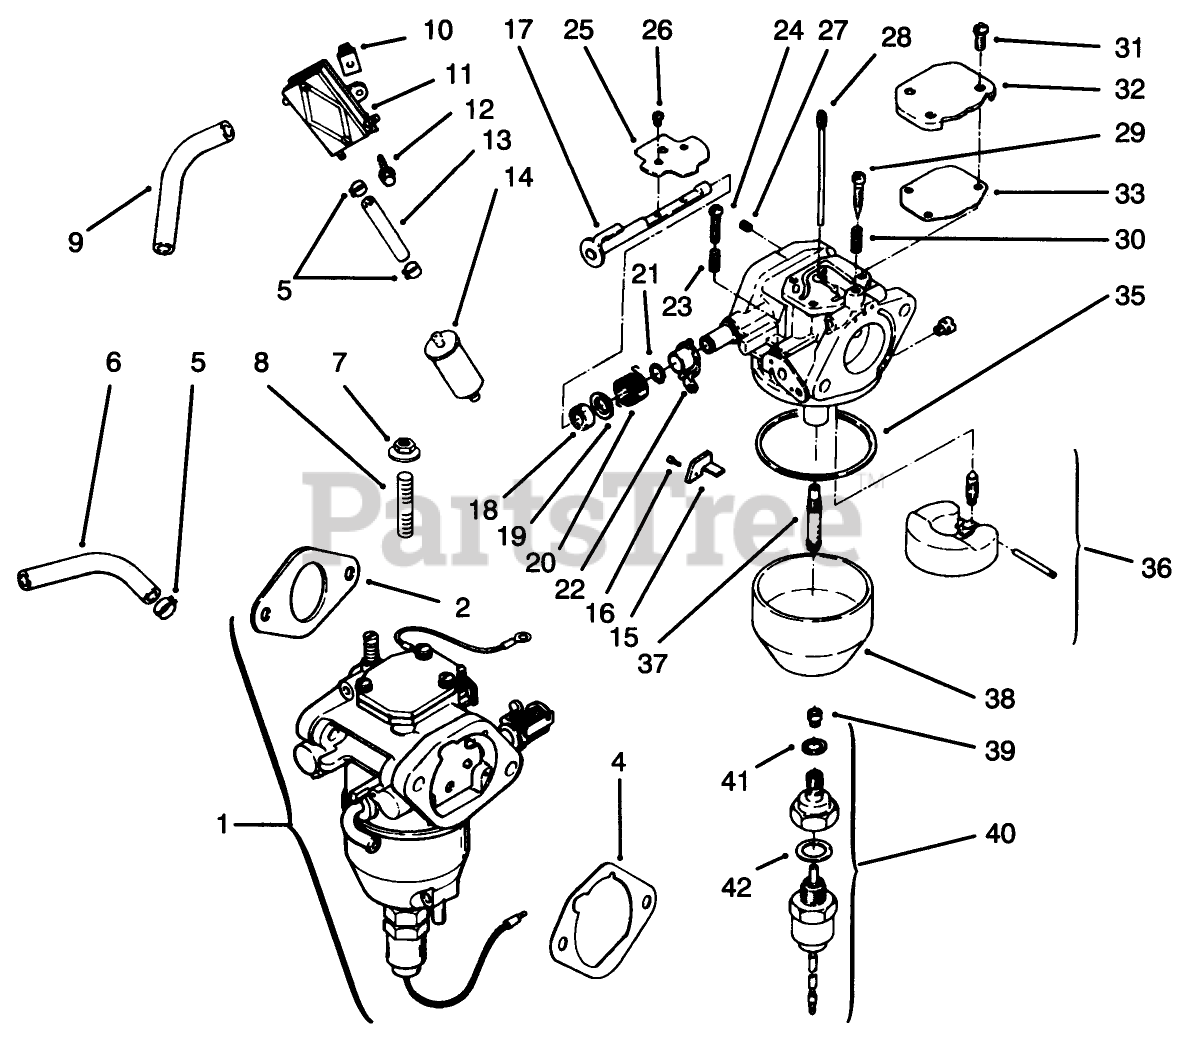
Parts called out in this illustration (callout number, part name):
1	Kit-Carb INCL 2/4/15-42 (Only On: 72103)
2	Gasket-Carburetor (Only On: 72103)
4	Gasket-A/C Base (Only On: 72103, 72083)
5	Clamp
6	Line-Fuel 10 1/2" (Only On: 72103, 72083)
8	Stud M6x1.0x95 (Only On: 72103, 72083)
9	Line-Fuel 12" (Only On: 72103)
11	Pump-Fuel
13	Line-Fuel 3 1/2" (Only On: 72103)
14	Filter-Fuel (Only On: 72042,72043,72062,72063)
15	Bracket-Throttle Stop (Only On: 72103, 72083)
16	Screw M2.5X45X5.5 (Only On: 72103)
17	Shaft-Choke (Only On: 72103, 72083)
18	Washer (Only On: 72103, 72083)
19	Collar-Choke (Only On: 72103, 72083)
20	Spring-Choke Return (Only On: 72103, 72083)
21	Ring-Choke Lever (Only On: 72103)
22	Lever-Choke (Only On: 72103)
23	Spring-Throttle Screw (Only On: 72103, 72083)
24	Screw-Throttle Adjust (Only On: 72103, 72083)
25	Valve-Choke (Only On: 72103)
26	Screw-Throttle Shaft (Only On: 72103, 72083)
27	Jet-Air Bleed (Only On: 72103)
28	Jet-Slow (Only On: 72103)
29	Screw-Idle Adjust (Only On: 72103, 72083)
30	Spring-Idle Adjust Screw (Only On: 72103)
31	Screw (Only On: 72103)
32	Cover-Passage (Only On: 72103, 72083)
33	Gasket-Passage Cover (Only On: 72103, 72083)
35	Gasket-Float Chamber (Only On: 72103)
36	Kit-Float Repair (Only On: 72103)
37	Nozzle-Main (Only On: 72103,72083)
38	Chamber-Float (Only On: 72103)
39	Jet-Main (Only On: 72103)
40	Kit-Solenoid INC 41-42 (Only On: 72103, 72083)
41	Gasket-Chamber Screw (Only On: 72103)
42	Gasket-Solenoid (Only On: 72103, 72083)
